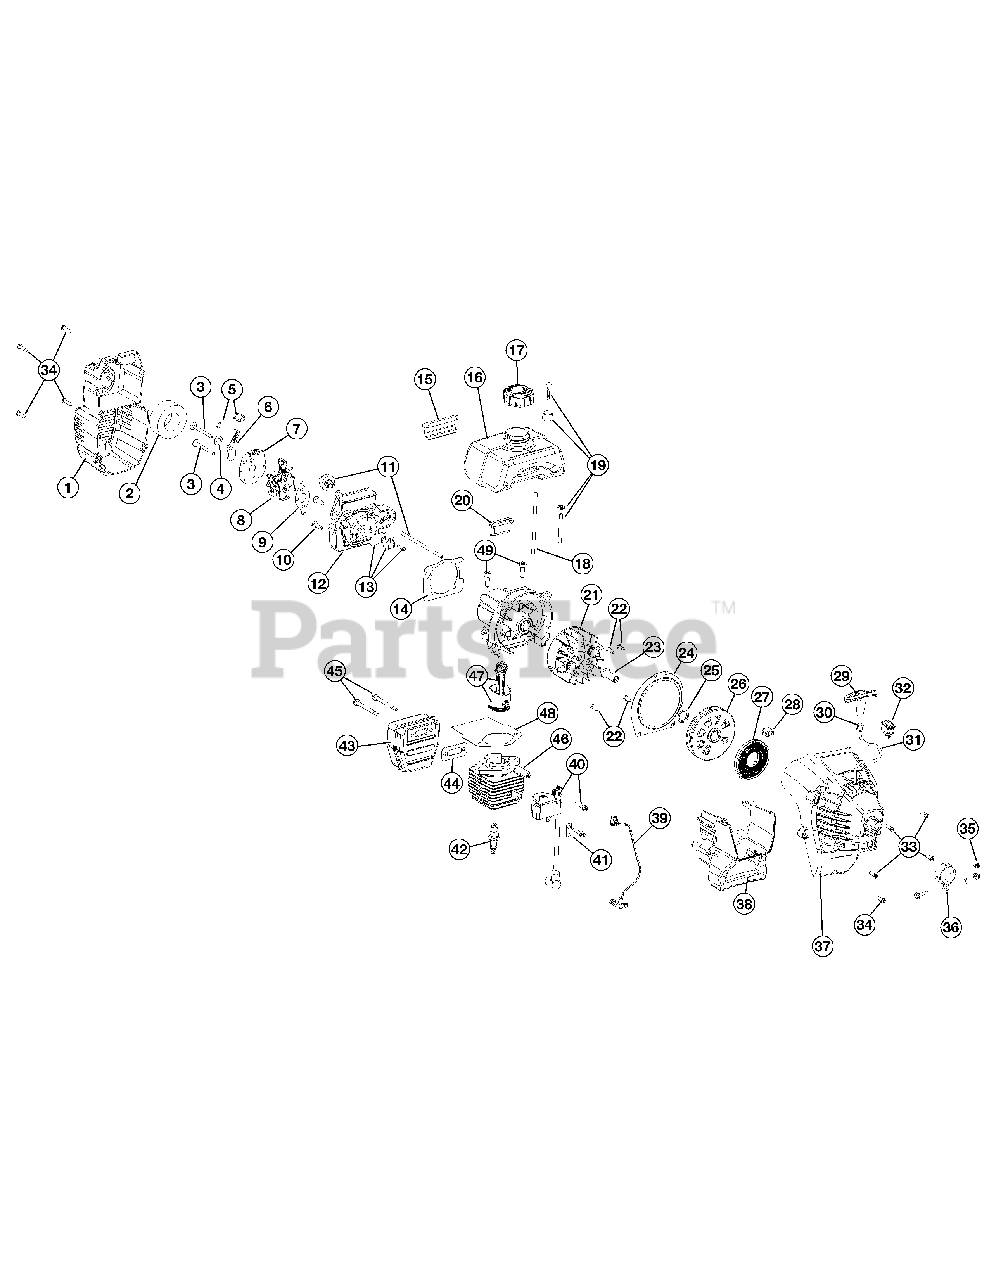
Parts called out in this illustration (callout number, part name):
1	Air Cleaner Cover Assembly (includes 2 & 34)
2	Air Cleaner Filter
3	Carburetor Mounting Screws
4	Wavey Washer
5	Choke Knob & Screw
6	Choke Lever Assembly (includes 5)
7	Choke Lever & Plate (includes 6)
8	Carburetor Assembly (includes 9 & 19)
9	Carburetor Gasket
10	Carb Mount Screw
11	Primer and Hose Assembly
12	Carburetor Mount Assembly (Includes 10, 13 & 14)
13	Reed Assembly
14	Carburetor Mount Gasket
15	Rear Mounting Pad
16	Fuel Tank Assembly (includes 17-19)
17	Fuel Cap Assembly
18	Fuel Return Line
19	Fuel Line Assembly
20	Front Mounting Pad
21	Flywheel Assembly
22	Plate Screw
23	Square Nut Drive
24	Pressure Plate (includes 22 & 28)
25	Palnut
26	Recoil Pulley Assembly (includes 25 & 31)
27	Recoil Spring
28	Eyelet Retainer
29	Pull Handle
30	Rope Guide
32	Switch Assembly (includes 39)
33	Housing Screw
34	Cover Screw
35	Anti Rotation Screw
36	Clamp Assembly (includes 35)
37	Starter Housing Assembly (includes 22 & 24-36)
38	Shroud Extension and Stand (includes 34)
39	Wire Lead
40	Module Assembly
41	Ground Tab
42	Spark Plug
43	Muffler Assembly (Includes 44, 45 & Spark Arrestor)
44	Exhaust Gasket
45	Muffler Mounting Bolt Assembly
46	Cylinder Assembly (includes 48 & 49)
47	Piston & Rod Assembly
48	Cylinder Gasket
49	Cylinder Bolt
